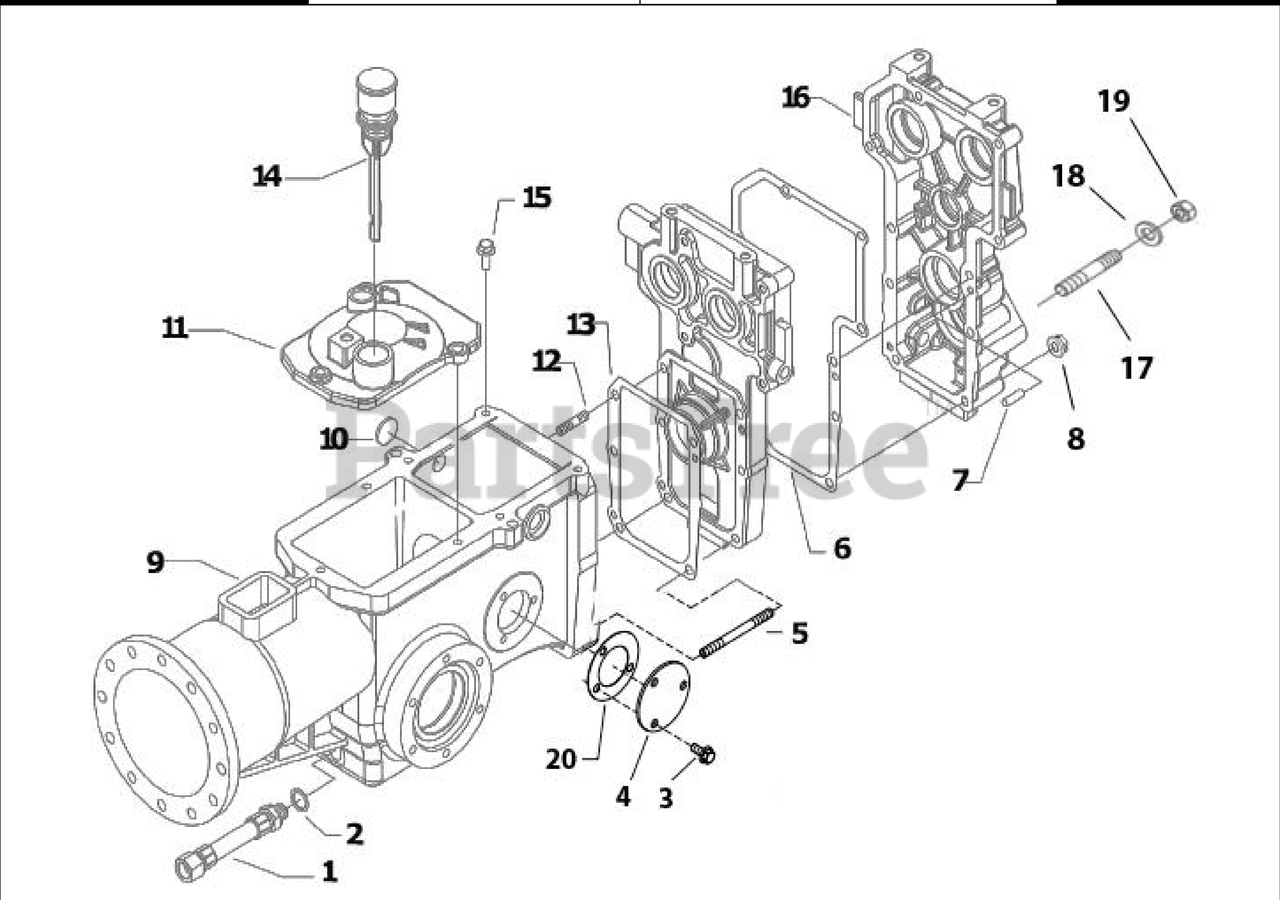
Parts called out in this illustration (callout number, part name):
1	SUCTION HOSE
2	COPPER WASHER 16.7x22/1.5
3	SCREW VITE TE C/F M6X12 DIN 6921
5	STUD BOLT M8X98X16X28 8G
6	FLANGE GASKET
7	CYLINDRICAL PLUG
8	SELFLOCK NUT M8 6S
9	GEARBOX CASE
10	PLUG 22 DIN 470
11	GEARBOX HOUSING TOP COVER
12	STUD BOLT M8X88X16X28 8G
13	GASKET
14	OIL CAP COMPLETE
15	SCREW TE C/F M8X20 DIN 6921
16	REAR END COVER
17	PTO STUD M12X1.25X12X64
18	WASHER DOMED
19	NUT M12X1.25 (Torque to 60 FT LBS)
20	GASKET
